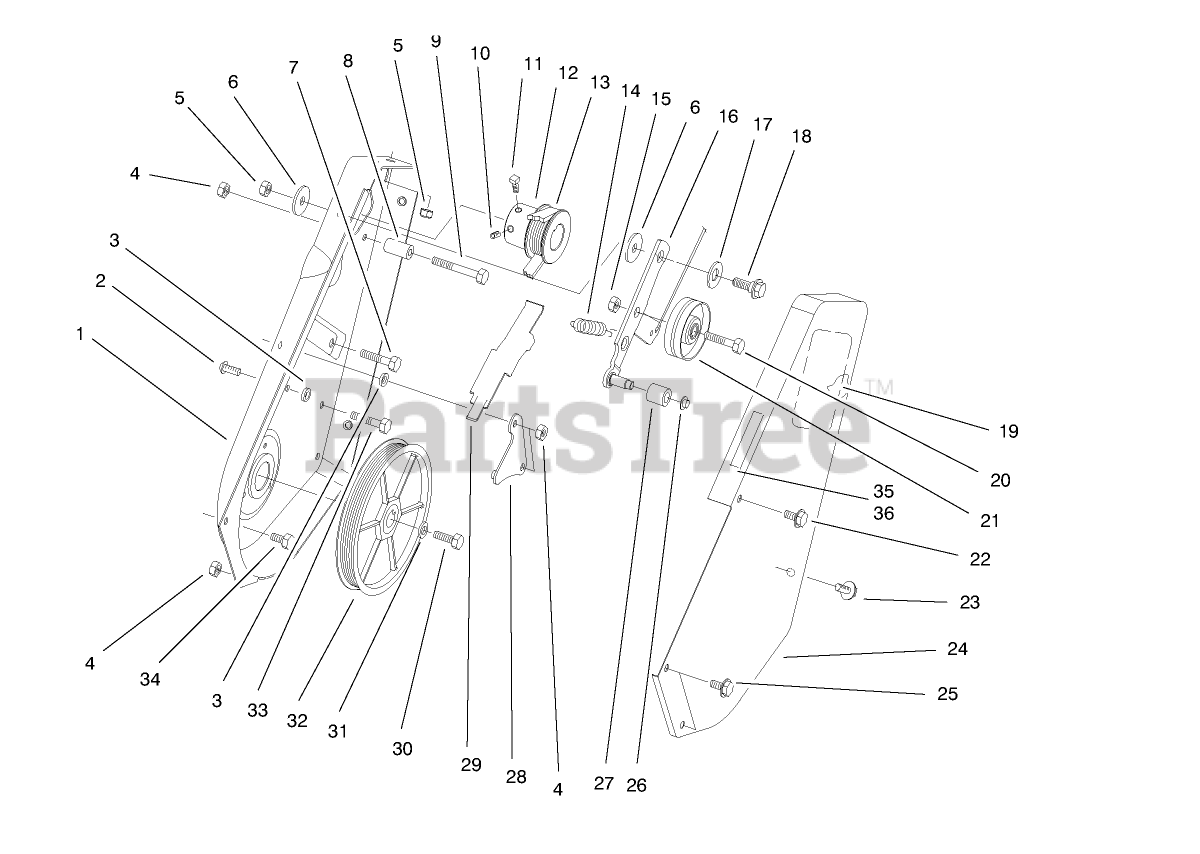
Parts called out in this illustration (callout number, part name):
2	SCREW-HSBH
3	SPACER-PLATE, PIVOT
4	NUT-LOCK, NI
5	NUT-LOCK, NI
6	WASHER-PIVOT
7	SCREW-HH
8	SLEEVE-GUIDE, BELT
9	SCREW-HH
10	SCREW-HSH
11	SCREW-SQH
12	ENGINE PULLEY
13	BELT - DRIVE
14	SPRING-EXTENSION
15	NUT-LOCK, CONE
16	IDLER ARM ASM
17	WASHER
18	SCREW-SHOULDER
19	DECAL
20	SCREW-HH
21	PULLEY-IDLER
22	SCREW-HWH, TAP
23	SCREW
25	SCREW-HWH
26	NUT-PUSH
27	ROLLER-BRAKE
28	PIVOT PLATE ASM
29	BRAKE-ARM
30	SCREW-HH
31	WASHER-BELLEVILLE
32	ROTOR PULLEY ASY
33	SCREW-HH
34	SCREW-SHH
36	DECAL-HOT
